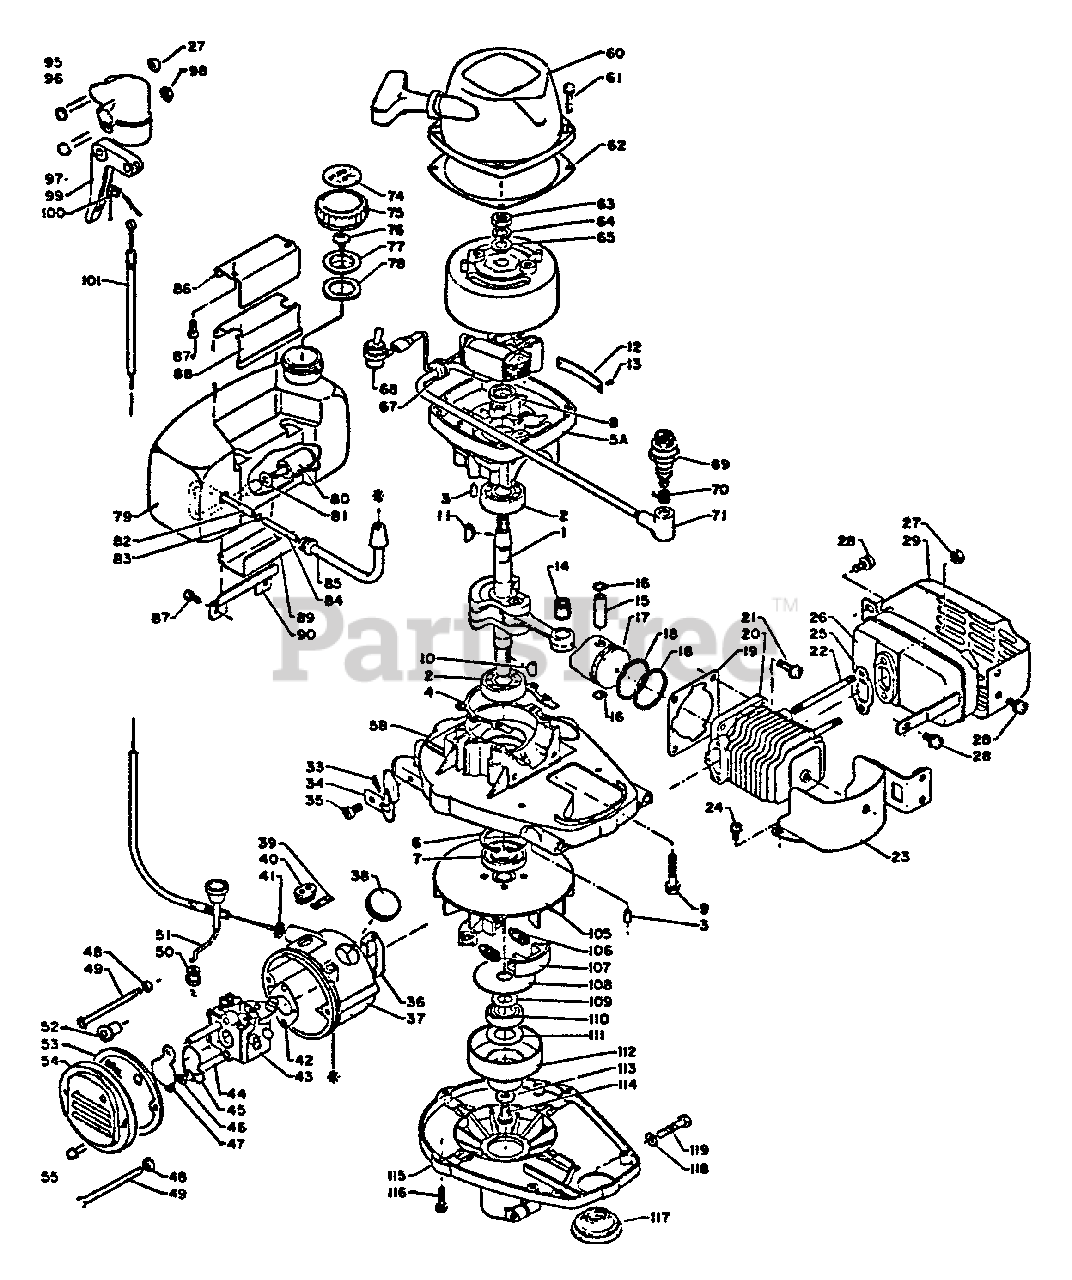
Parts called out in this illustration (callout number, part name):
1	CRANKSHAFT ASSY
2	BEARING, BALL - 6201
3	PIN - LOCATING
4	GASKET, CRANKCASE
5	CRANKCASE KIT
6	RING, RETAINING - 32
7	SEAL, OIL
8	SEAL, OIL
9	SCREW - 5X28
12	PLATE, MODEL
13	RIVET
14	BEARING, NEEDLE
15	PIN, PISTON
16	RING, RETAINING
17	PISTON
18	RING, PISTON
19	GASKET, CYLINDER
20	CYLINDER
21	SCREW - 5X16
22	STUD
23	SHIELD, CYLINDER
24	SCREW - 4X8
25	GASKET, EXHAUST
26	MUFFLER
27	LOCKNUT - 5
28	SCREW - 5X10
29	COVER, MUFFLER
33	LABEL - STOP
34	BRACKET, SWITCH
35	SCREW - 5X10
36	GASKET, INTAKE
37	CASE, CARBURETOR
38	PLUG
39	LABEL - CAUTION
42	GASKET, INTAKE
43	CARBURETOR
44	SPACER
45	SHUTTER, CHOKE
46	WASHER
47	PLATE, PREVENT
50	GROMMET
51	ROD, CHOKE
52	GROMMET
53	FILTER, AIR
54	COVER, AIR FILTER
55	SCREW - 4X12
60	STARTER ASSY
61	SCREW - 4X20
62	GASKET, STARTER
64	LOCKWASHER - 8
68	IGNITION SWITCH ASSY
69	SPARK PLUG -- BM-6A
70	TERMINAL, SPARK PLUG CAP
71	CAP, SPARK PLUG
74	LABEL - FUEL MIX
75	CAP
77	HOLDER, VENT
78	GASKET, CAP
79	TANK, FUEL
80	FILTER, FUEL
81	WASHER - 6
82	PIPE - FUEL
84	CONNECTOR, PIPE
85	PIPE - FUEL
86	BRACKET, FUEL TANK
87	SCREW - 4X8
88	CUSHION, FUEL TANK
89	CUSHION, FUEL TANK
90	BRACKET, FUEL TANK
95	BRACKET, TRIGGER
96	SCREW - 5X30
97	SCREW - 5X25
99	TRIGGER, THROTTLE
100	SPRING, TRIGGER
101	CABLE, THROTTLE
105	FAN
106	SPRING, CLUTCH
107	SHOE, CLUTCH
108	PLATE, CLUTCH
109	WASHER, CLUTCH
110	BEARING, BALL - 8000
111	WASHER, CLUTCH
112	DRUM, CLUTCH
113	WASHER - 6
114	SCREW - 6X10
115	CASE, FAN
116	SCREW - 4X18
117	SEAL, DUST
119	BOLT - 5X25
